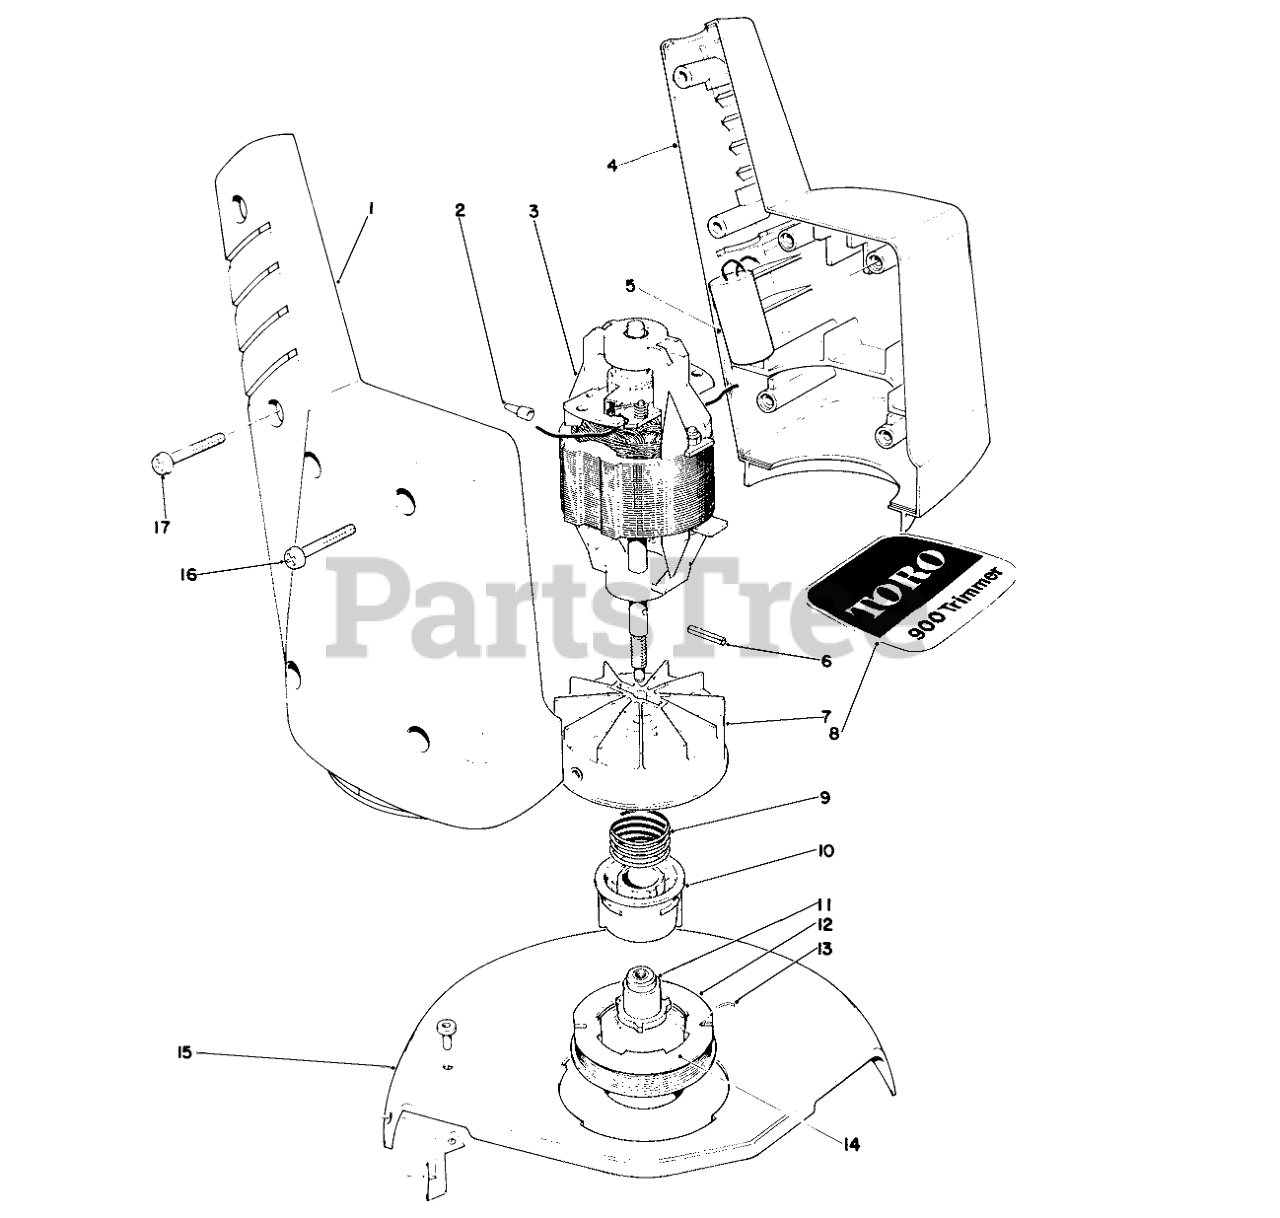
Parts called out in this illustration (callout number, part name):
1	Right Motor Housing
2	CONNECTOR WIRE JOINT
3	Motor
4	RH MOTOR HSG
5	Suppressor
6	COIL PIN
7	FAN HUB ASM
8	Toro 900 Decal
9	SPRING-COMPRESSION
10	CORE - SPOOL
11	Driver
12	SPOOL CAP
13	.040" Cutting Line in Coil
14	Prewound Spool
15	Shield with Cut-off Blade
16	SCREW-PPH
